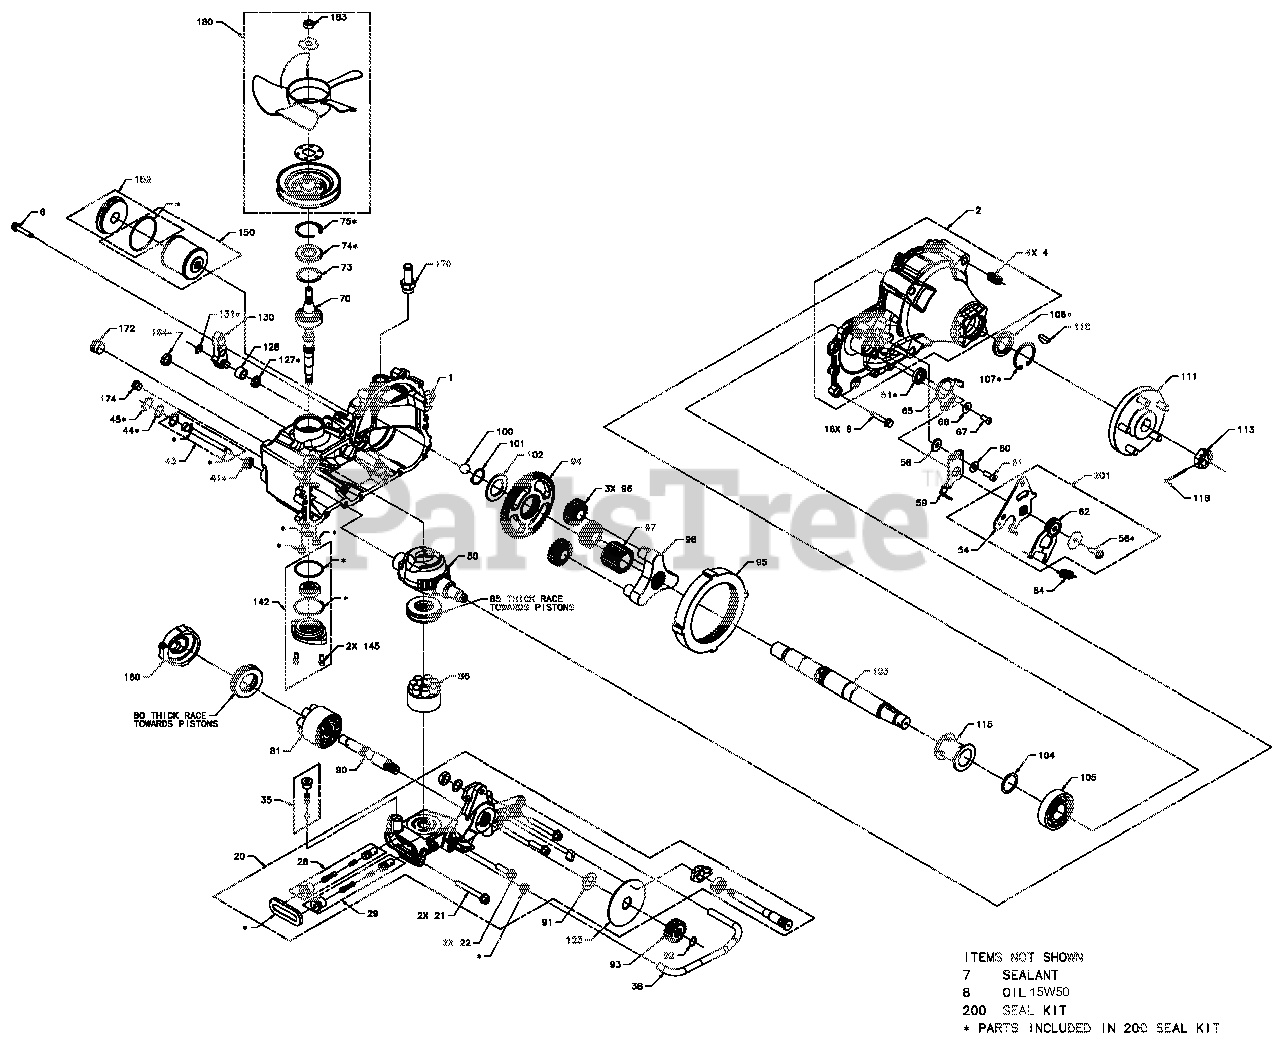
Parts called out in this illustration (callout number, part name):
1	Kit, Housing, Main, LH
2	Kit, Housing, Side, LH
7	SEALANT TUBE 10.1OZ.
8	FLUID, HYDRO 15W50 QT
20	CENTER SECTION L(03935300)
28	HG SHOCK VALVE KIT
29	HG SHOCK VALVE KIT
35	HG CHARGE RELIEF VALVE KIT
38	Tube, Filter LH
41	Seal, Lip 12 x 24 x 5 TC
43	Kit, Bypass Actuator
44	Spring, Wave
50	Swash Plate, 16CC Machined
54	Arm, Control LH
56	TWHCS 5/16-24 X 1.00
58	SPACER
59	ARM, NEUTRAL RIGHT
60	WASHER
61	SHCS 5/16-24X1 PATCH
62	Assembly, RTN Uni-Directional
64	RTN SPRING HG 51605
65	Plate, Stop, LH
66	WASHER
70	INPUT SHAFT HG 71941
74	Seal, Lip 25 x 52 x 7 TC
75	Ring, Retaining, Internal
81	KIT, MOTOR BLOCK
90	Shaft, Motor
92	RING, RET 62 EXT
98	Carrier
100	BALL, .75
102	Spacer, Thrust Axle
103	SHAFT, AXLE
105	BEARING,BALL 35 X 80 X 21 6307
106	HG SEAL LIP 1.375X2.062X.250
107	RING, RETAINING
110	KEY, WOODRUFF 5/16 X 1
111	HG 5 BOLT HUB KIT
113	HG HEX NUT 1-20 SLOTED
116	PIN, COTTER 9/64 X 2 EXTENDED
123	Rotor, Brake
130	BRAKE ARM HG 53018
131	Ring, Retaining
142	CHARGE COVER KIT
150	FILTER,HYD OIL W/ORING ZT-54OO
152	HG FILTER PLUG KIT
160	Plate, Motor Swash
164	Seal, Plug
170	Fitting, 7/8-14 SAE .625 Beaded
172	Plug, 7/8-14 Metal
174	Plug, 9/16-18, Metal
180	PULLEY/FAN KIT HG 71906
183	KIT, PUMP SHAFT 15MM KEYW
200	SEAL KIT HG 71945
201	KIT, RTN, LH, UNI-DIRECTIONAL
